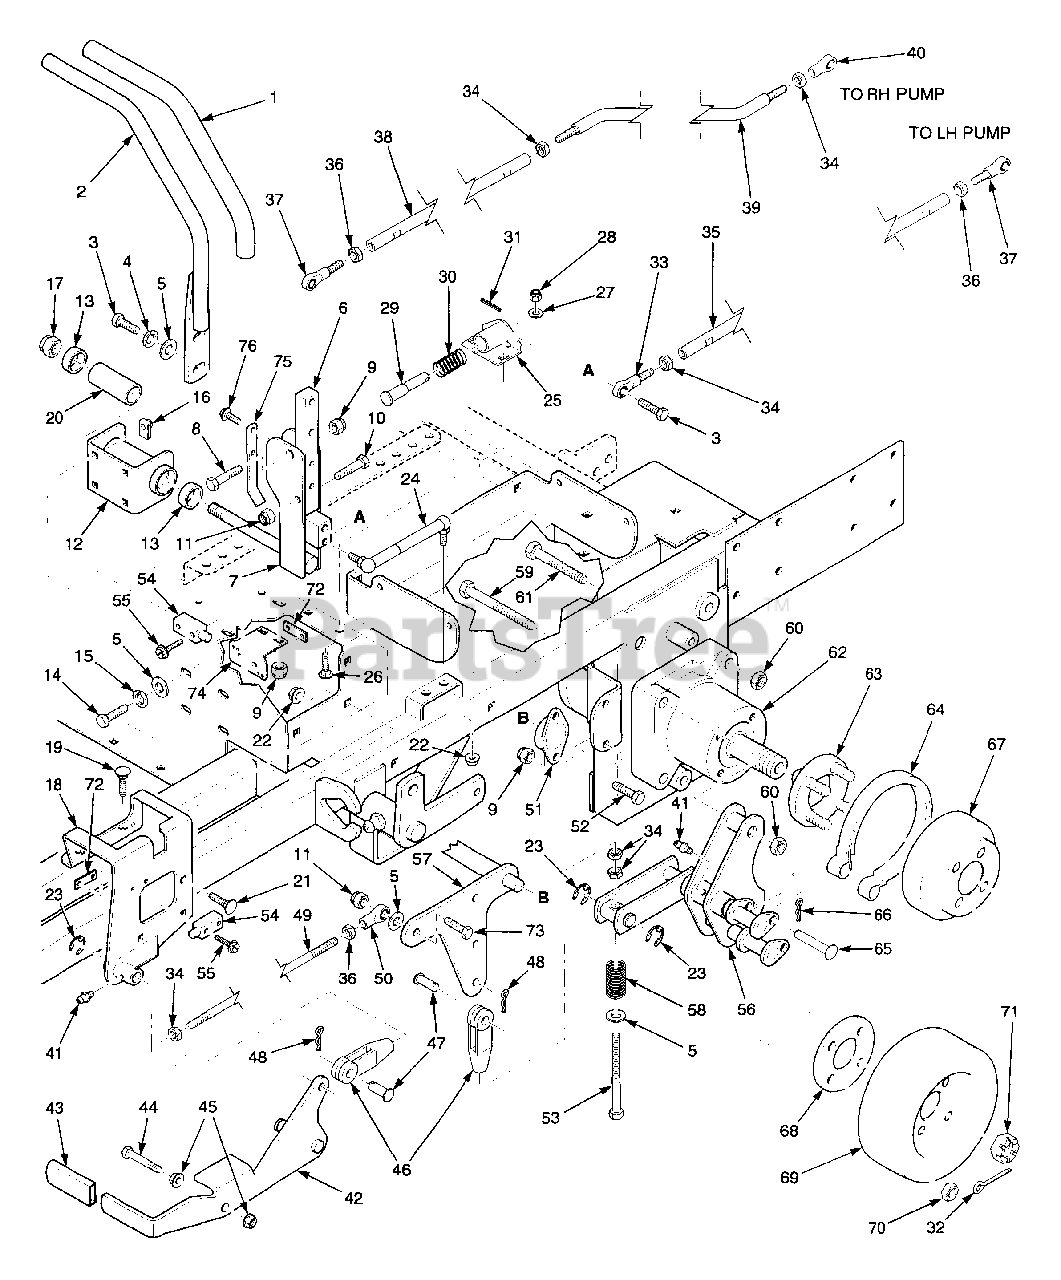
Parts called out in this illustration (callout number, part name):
1	Grip, Handle Bar
2	Handle Bar
3	Bolt, Hex Head 3/8-16 x 1-1/4"
4	Lockwasher, 3/8"
5	Flatwasher. 3/8" (.391 x .938 x .105)
6	Bar, Control Lever
7	Control Lever
8	Bolt, Hex Head 5/16-18 x 2"
9	Nut, Hex Elastic Stop 5/16-18
10	Bolt, Hex Head 3/8-16 x 2"
11	Nut, Hex Elastic Stop
12	Bracket, Control
13	Ball Bearings, Neutral Return
14	Bolt, Hex Head 5/16-18 x 1-1/4"
15	Lockwasher, 5/16"
16	U-Nut, 5/16-18
17	Nut, Hex Elastic Stop 5/8-11
18	Bracket, Control Lever LH
19	Bolt, Carriage 5/16-18 x 1"
20	Spacer, Bearing
21	Bolt, Carriage 5/16-18 x 3/4"
22	Nut, Hex Serrated Flange 5/16-18
23	Ring, Retaining 5/8" External "E"
24	Gas Damper
25	Bracket, Neutral Return
26	Bolt, Carriage 1/4-20 x 3/4"
27	Flatwasher, 1/4" (.312 x .750 x .065)
28	Nut, Hex Elastic Stop 1/4-20
29	Pin, Retaining Spring
30	Spring
31	Roll Pin, Spring 5/32 x 3/4"
32	Pin, Cotter 9/16 x 1-1/2"
33	Rod End, Male 3/8-24 RH THD.
34	Nut, 3/8-24 RH THD.
35	Tube, Control Link
36	Nut, Hex 3/8-24 LH THD.
37	Rod End, Male 3/8-24 LH THD.
38	Tube, Control Link
39	Rod, Control
40	Ball Joint, RH THD.
41	Grease Fitting
42	Lever, Parking Brake
43	Grip, Parking Brake
44	Bolt, Hex Head 3/8-16 x 2-3/4"
45	Nut, Hex Serrated Flange 3/8-16
46	Clevis, Traction Control
47	Pin, Clevis 3/8-16 x 1-1/16"
48	Pin, Hair Pin Cotter 5/32 x 3/4"
49	Rod, Parking Brake
50	Rod End, LH THD.
51	Bushing, Self Align
52	Bolt, Hex Head 5/16-18 x 3/4"
53	Bolt, Hex Head 3/8-24 x 5-1/4", 2-3/4" Thread
54	Switch
55	Screw, Hex SLTD WSHR Head #10-32 x 3/4"
56	Brake Linkage, LH
57	Bellcrank, Brake Actuator
58	Spring
59	Bolt, Hex Head 1/2-13 x 3-1/2"
60	Locknut, Hex 1/2-13 Center Lock
61	Bolt, Hex Head 1/2-13 x 2-1/2"
62	Wheel Motor, Ross
63	Wheel Hub Assembly
64	Brake Band Assembly
65	Pin, Clevis 3/8" Dia. x 2"
66	Pin, Cotter 5/32 x 3/4"
67	Brake Drum
68	Spacer, Wheel
69	Wheel Assembly 23 x 10.5-12 4 Ply
70	Lug Nut, 1/2-20
71	Nut, Hex Castle
72	Plate, Threaded
73	Bolt, Hex Head 3/8-16 x 1-1/2"
74	Bracket, Switch Mounting
75	Bracket, Switch Actuator
76	Bolt, Hex Serrated Flange 5/16-18 x 3/4"
